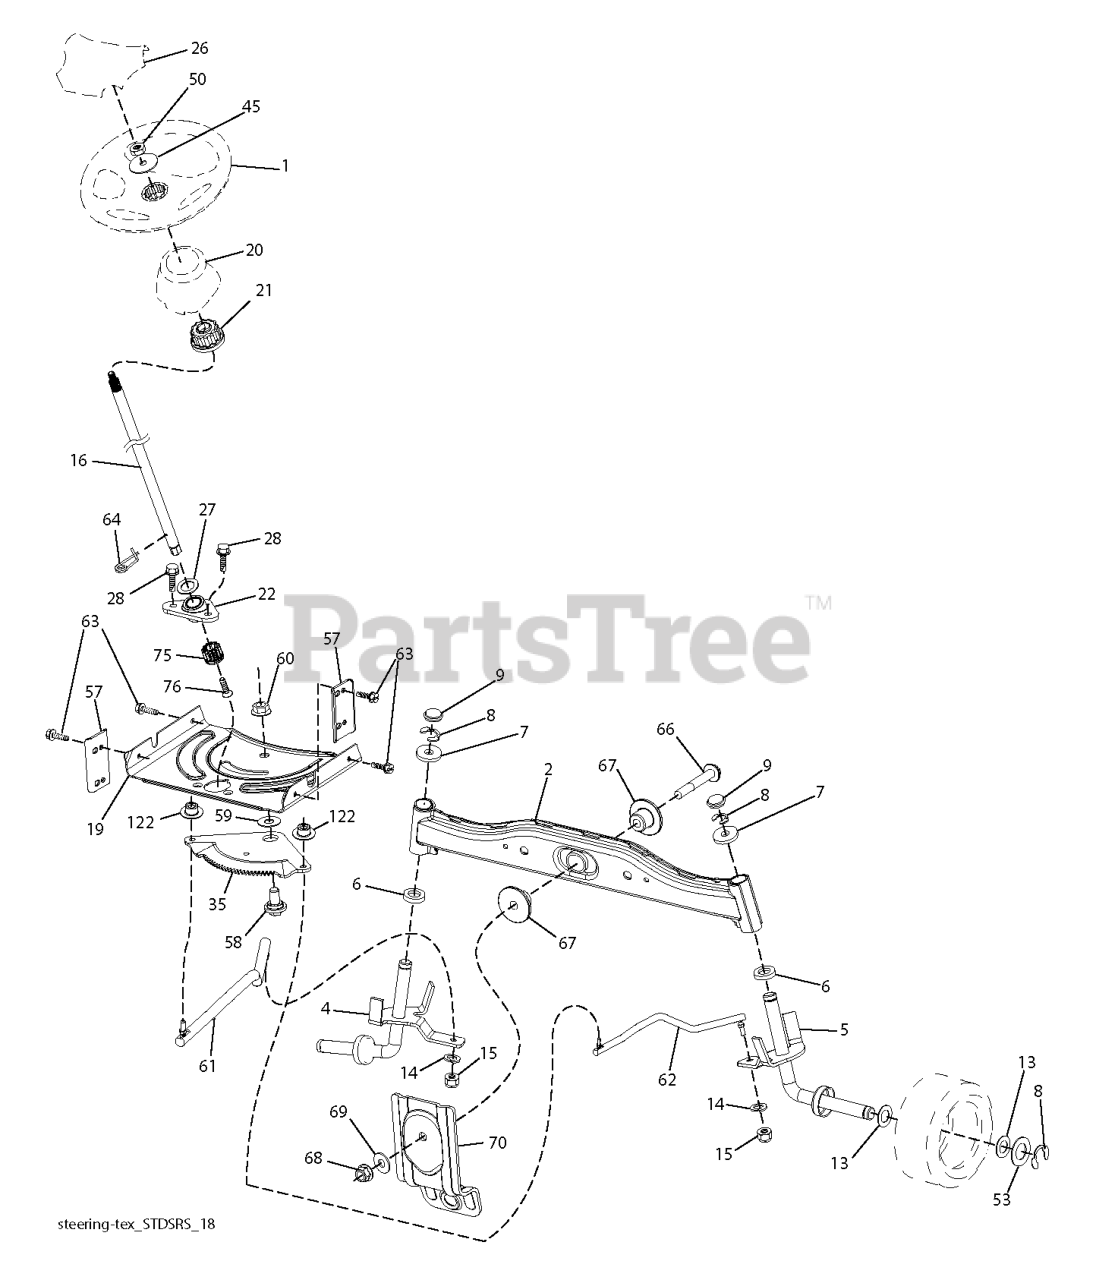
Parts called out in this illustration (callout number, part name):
1	WHEEL.STEERING.STDSRR.BLK/OV
2	AXLE.CAST.IRON
4	SPINDLE.WELDED.LH.15"TEX
5	SPINDLE.WELDED.RH.15"T
6	WASHER THRUST
8	RING CLIP
9	CAP.SPINDLE.BLACK
14	SLW 3/8 STD
15	NUT CROWNLOCK 3/8-24
16	SHAFT.STEER.2HIGH.SPLND.PLATED
19	PLATE.STEER.DDL.NLT/NG
20	BOOT.STRNG.PREDATOR.YT/GT.428
21	ADAPTER.WHEEL.STEER.SPLND.ALUM
22	BEARING.SHAFT.STEER.LOWER.625
26	INSERT, WHEEL STEERING
27	WASHER LT
28	SCREW, 3/8-16X3/4
35	GEAR.SECTOR.PLATE.DDL.
45	WASHER.3/8ID.2-3/8OD.12GA.PLTD
50	NUT LOCK FLG 3/8-16 UNC
53	WASHER.HARDENED
57	BRACKET.UPSTOP.TEX
58	BOLT.SHOULDER.SECTOR.P
59	WASHER.THURST.SECTOR.S
60	NUT FLANGE LOCK 5/8-11
61	LINK.ASM.DRAG.ADJUST.LH.PLATED
62	LINK.ASM.DRAG.ADJUST.RH.PLATED
63	SCREW
64	RETAINER.CLIP.SPRING.S
66	BOLT HEX FGHD 7/16-14 X 3 SERR
67	BUSHING.PM.FRONT AXLE
68	NUT.LOCK.FLANGE.7/16
69	WASHER.1.5X.505X.118
70	BRACKET.FRT.DECK.SUSP.RR.MT431
75	PINION.ZINC PLATED
76	SCREW HEAD SOCKET LRVB
122	CAP.GEAR.SECTOR.TEX
